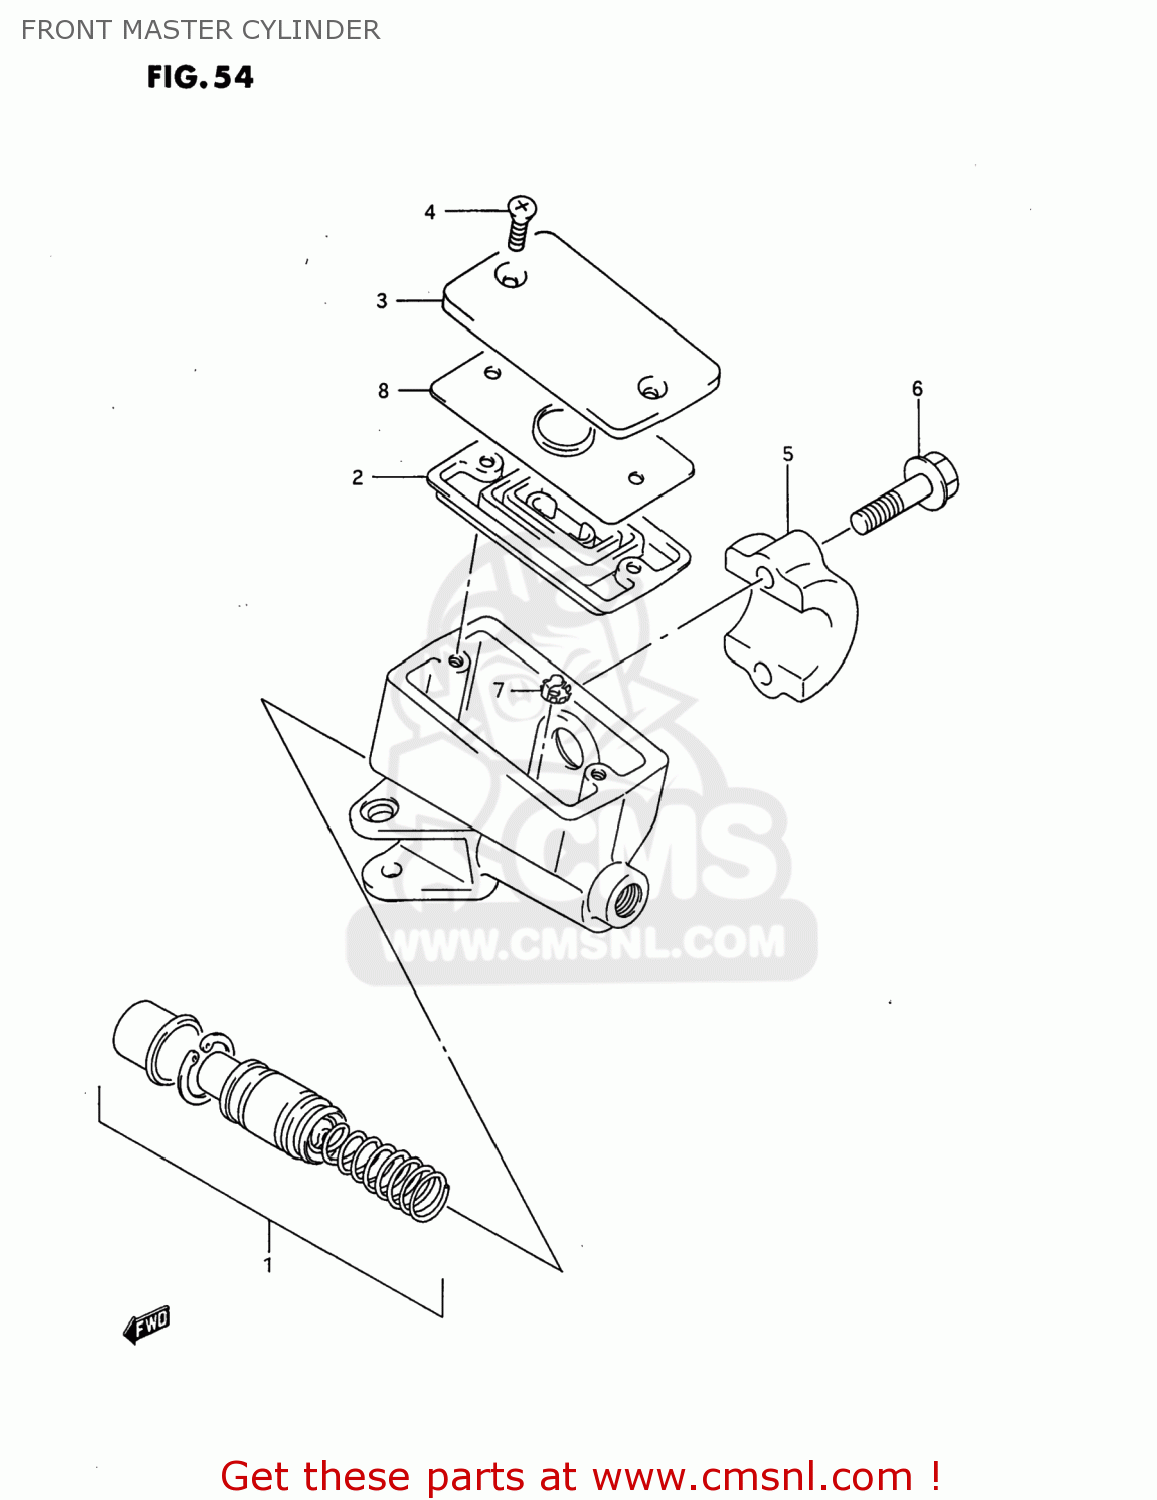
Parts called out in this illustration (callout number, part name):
1	PISTON & CUP SET
2	3
3	CAP
4	SCREW
5	HOLDER
6	BOLT(6X25)
7	PROTECTOR
8	PLATE,DIAPHRAGM
